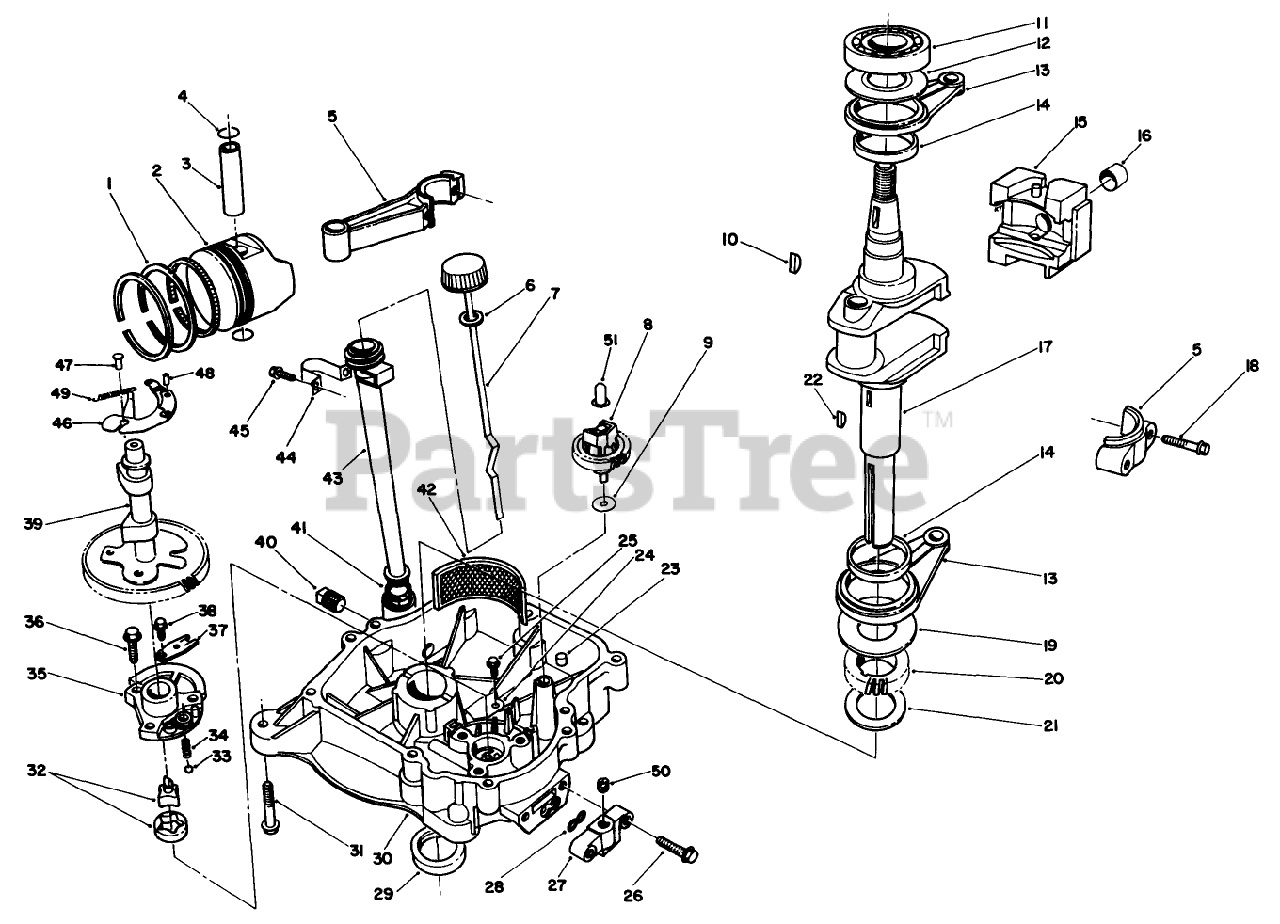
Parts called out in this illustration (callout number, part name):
1	Piston Ring Set
3	Pin-Piston
4	Ring-Snap
5	Connecting Rod Ass-y-Standard (includes item 44)
8	Governor ASM
11	Ball Bearing
13	Rod Incl #8
14	Bearing
15	Weight Complete (includes item 133)
16	Bushing
17	Crankshaft
21	Shim (1.18)
29	Oil Seal
31	Bolt-Flanged (8X45)
32	Pump ASM-Oil
35	Cover-Pump
36	Bolt-Flanged (8X25)
38	BOLT-FLANGED (6X10)
39	Camshaft
41	O-RING (16mm)
42	Filter-Oil
46	Decompressor
